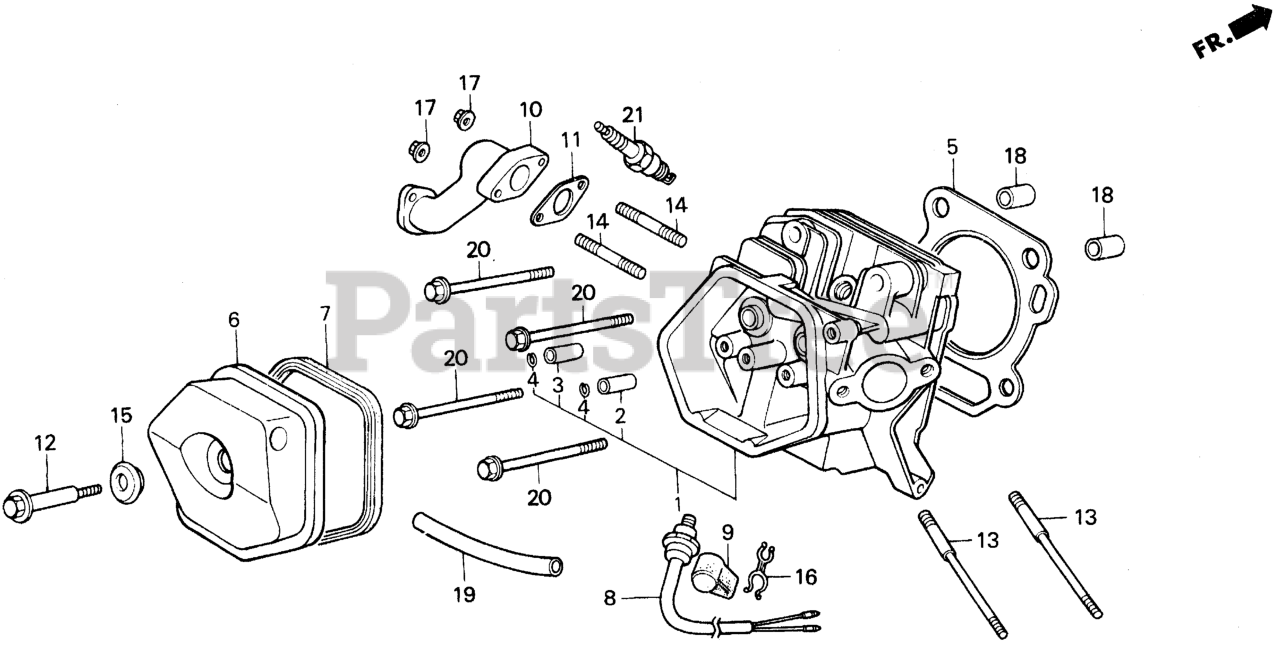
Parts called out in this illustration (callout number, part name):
1	CYLINDER HEAD
2	GUIDE, VALVE (OS)
4	CLIP, VALVE GUIDE
5	GASKET, CYLINDER HEAD
6	COVER, HEAD
7	GASKET, CYLINDER HEAD COVER
11	GASKET, EX. PIPE Use up to Engine SN 2949254.
11	GASKET, EX. PIPE (WACKER)
12	BOLT, HEAD COVER
13	BOLT, STUD (8X106)
14	BOLT, STUD
15	WASHER, HEAD COVER
17	NUT, FLANGE (8MM)
18	PIN A, DOWEL (12X20)
20	BOLT, FLANGE (10X80)
21	SPARK PLUG (BPR5ES-11) (NGK)
21	SPARK PLUG (W16EPR-U11) (DENSO)
21	SPARK PLUG (BPR5ES) (NGK)
21	SPARK PLUG (W16EPR-U) (DENSO)
21	SPARK PLUG (BPR6ES-11) (NGK)
21	SPARK PLUG (W20EPR-U11) (DENSO)
